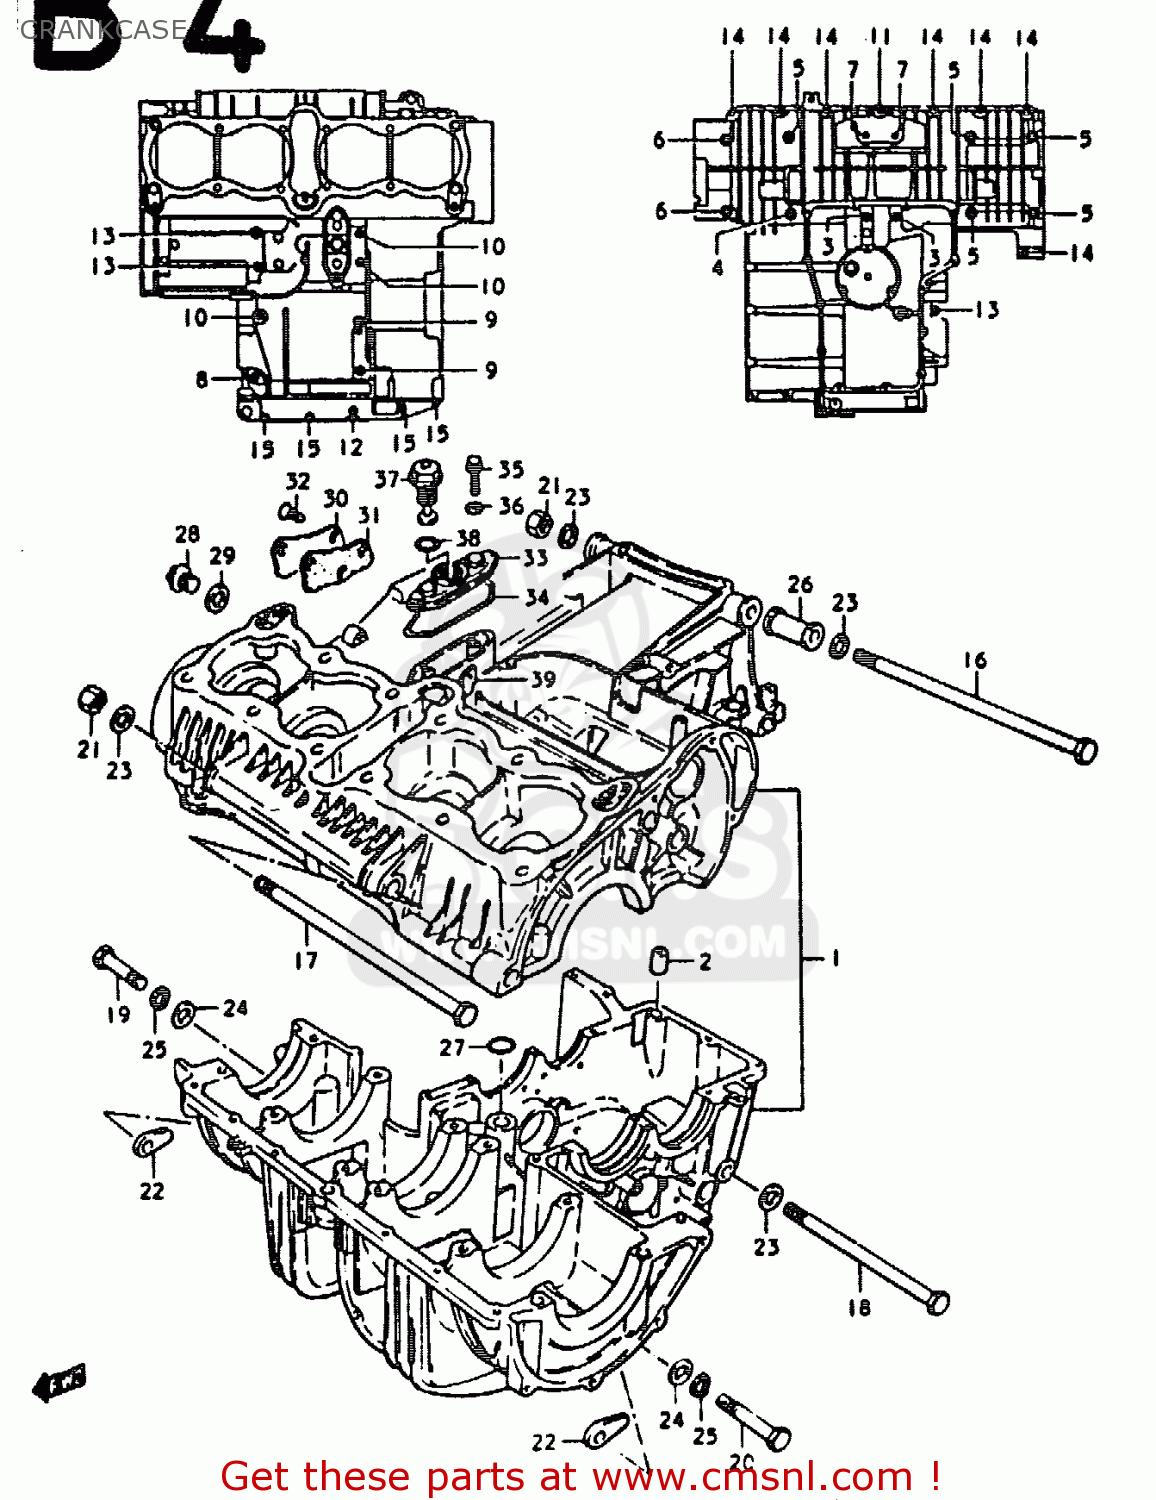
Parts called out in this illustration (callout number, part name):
1	CRANKCASE SET
2	PIN
3	BOLT
4	BOLT
5	BOLT 8X90
6	BOLT 8X65
7	BOLT
8	BOLT
9	BOLT
10	BOLT (6X75)
11	BOLT ,6X50
12	BOLT,UNDER
13	BOLT
14	BOLT 6X35
15	BOLT
16	BOLT 10X265
17	BOLT 10X250
18	BOLT(10X165)
19	BOLT 10X60
20	BOLT 10X60
21	NUT
22	NUT
23	WASHER
24	WASHER(10.5X20X3.2)
25	LOCK WASHER
26	SPACER,ENGINE MOUNT
27	O RING(D:3.2,ID:12.9)
28	PLUG (14X12)
29	GASKET(14X19.2X2) (NAS)
30	CAP,OIL GALLERY
31	GASKET,OIL GALLERY (MCA)
32	SCREW
33	HOUSING,OIL PRESSURE SWITCH
34	O RING,PRESSURE SWITCH HOUSING
35	BOLT
36	GASKET (NAS)
37	SWITCH ASSEMBLY
38	O RING(D:1.9,ID:18.8)
39	GROMMET,STARTING MOTOR
